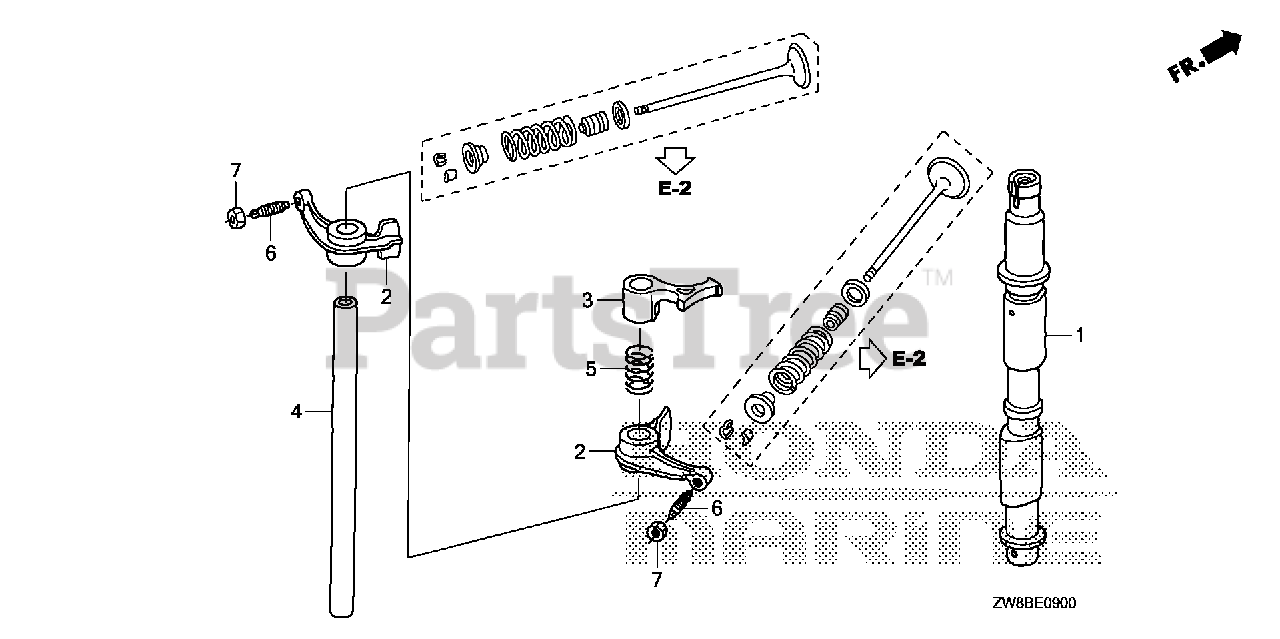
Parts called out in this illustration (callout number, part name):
2	ARM, VALVE ROCKER
3	ARM, FUEL PUMP ROCKER
4	SHAFT, ROCKER ARM
5	SPRING, ROCKER ARM
6	SCREW, TAPPET ADJ.
7	NUT, TAPPET ADJ.
